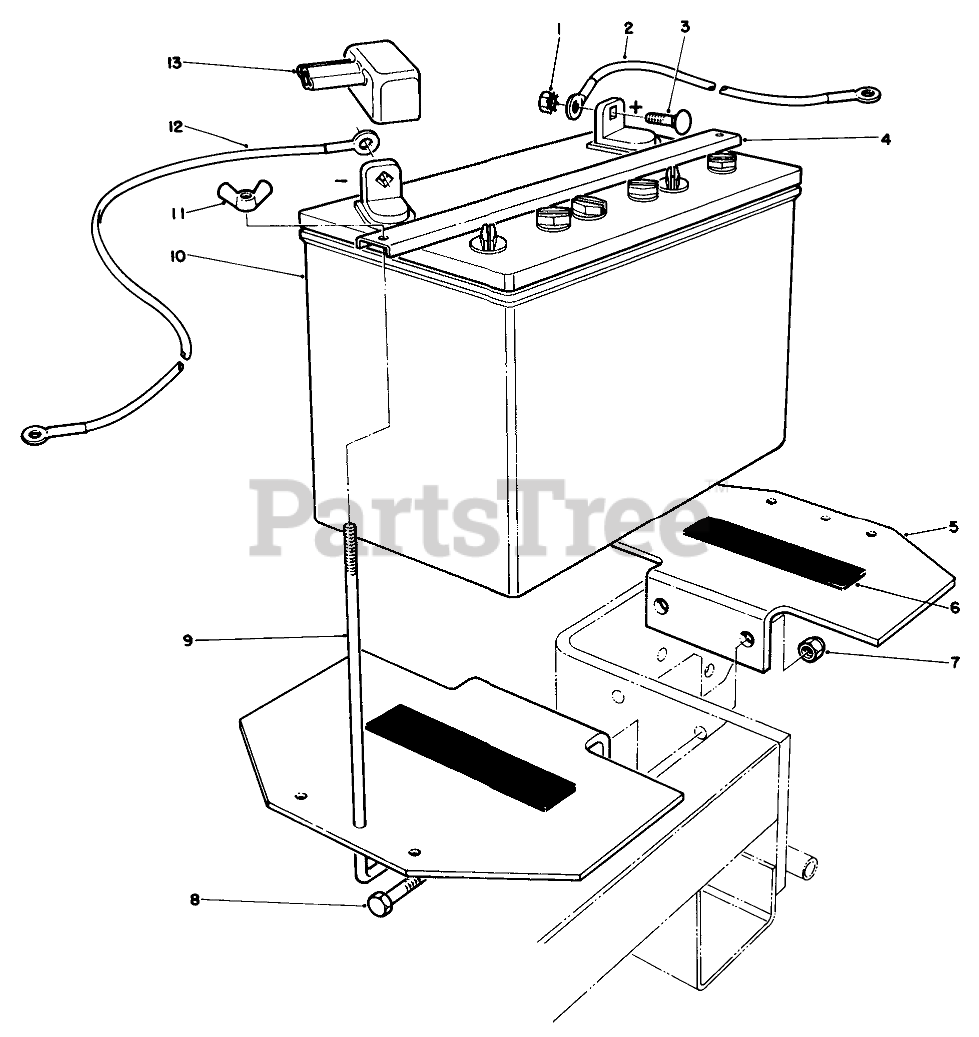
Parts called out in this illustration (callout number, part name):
1	NUT-KEPS
2	WIRE ASM
3	BOLT-CARR
4	BATTERY STRAP R/B
5	Holder-Battery
6	PAD-TANK, FUEL
7	NUT-LOCK, CONE
8	SCREW-HH
9	ROD-SUPPORT, BATTERY
10	Battery
11	WING NUT
12	WIRE ASM
13	BOOT-TERMINAL
